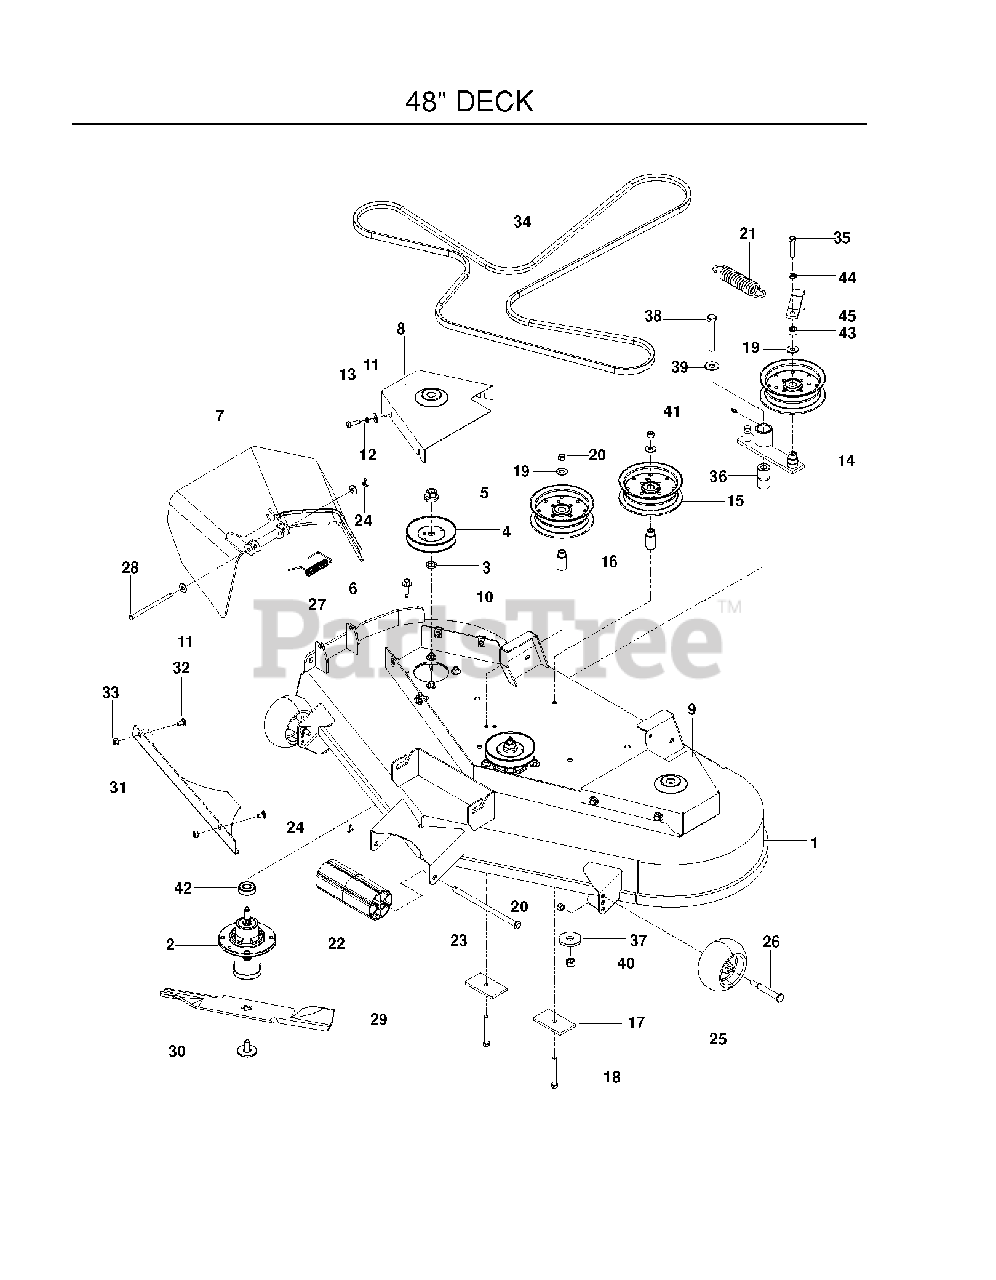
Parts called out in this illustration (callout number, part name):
1	DECK.W/DECALS.RAM.48.BLUE
2	MANDREL.DECK.ASSEMBLY
3	WASHER-SPACER
4	MANDREL PULLEY
5	LOCKNUT - 9/16
6	WASHER HEAD SCREW
7	DISCHARGE CHUTE 48"
8	BELTSHIELD - R.H. BLUE
9	BELTSHIELD - L.H. BLUE
10	U-CLIP 5/16-18 NUT RETAINER
11	WASHER 5/16 FLAT
12	WASHER 5/16 LOCK
13	HCS 5/16C X 1
14	IDLER ARM
15	PULLEY, IDLER
16	IDLER BUSHING
17	SUPPORT PLATE
18	HCS 3/8C X 3
19	WASHER 3/8 FLAT
20	NUT 3/8-16 NYLOC
22	NOSE ROLLER 48"
23	NOSE ROLLER ROD
24	COTTER PIN 1/8 X 3/4
25	GAUGE WHEEL
26	SHOULDER BOLT 1/2X2-5/8 ZD SPE
27	SPRING - TORSION
28	PIN-CLEVIS 5/16 DIA X 5.19 ZD
29	BLADE, 16-1/4" FUSION
30	BLADE BOLT ASSY-7/16" TB REPL
31	Confinement Plate, 48" Black
32	CARRIAGE BOLT 5/16C X 5/8"
33	NUT 5/16 NYLOC
34	BELT, DECK
35	HCS 3/8-16 X 1 3/4 GR5
36	PIVOT BUSHING
37	WASHER, SUPPORT
38	HCS 1/2C X 3 1/4
39	WASHER 1/2 FLAT
40	NUT 1/2-13 HEX NYLOC ZD
41	ZERK
42	BEARING, BALL
44	SLW 3/8 STD
45	GUIDE, BELT
